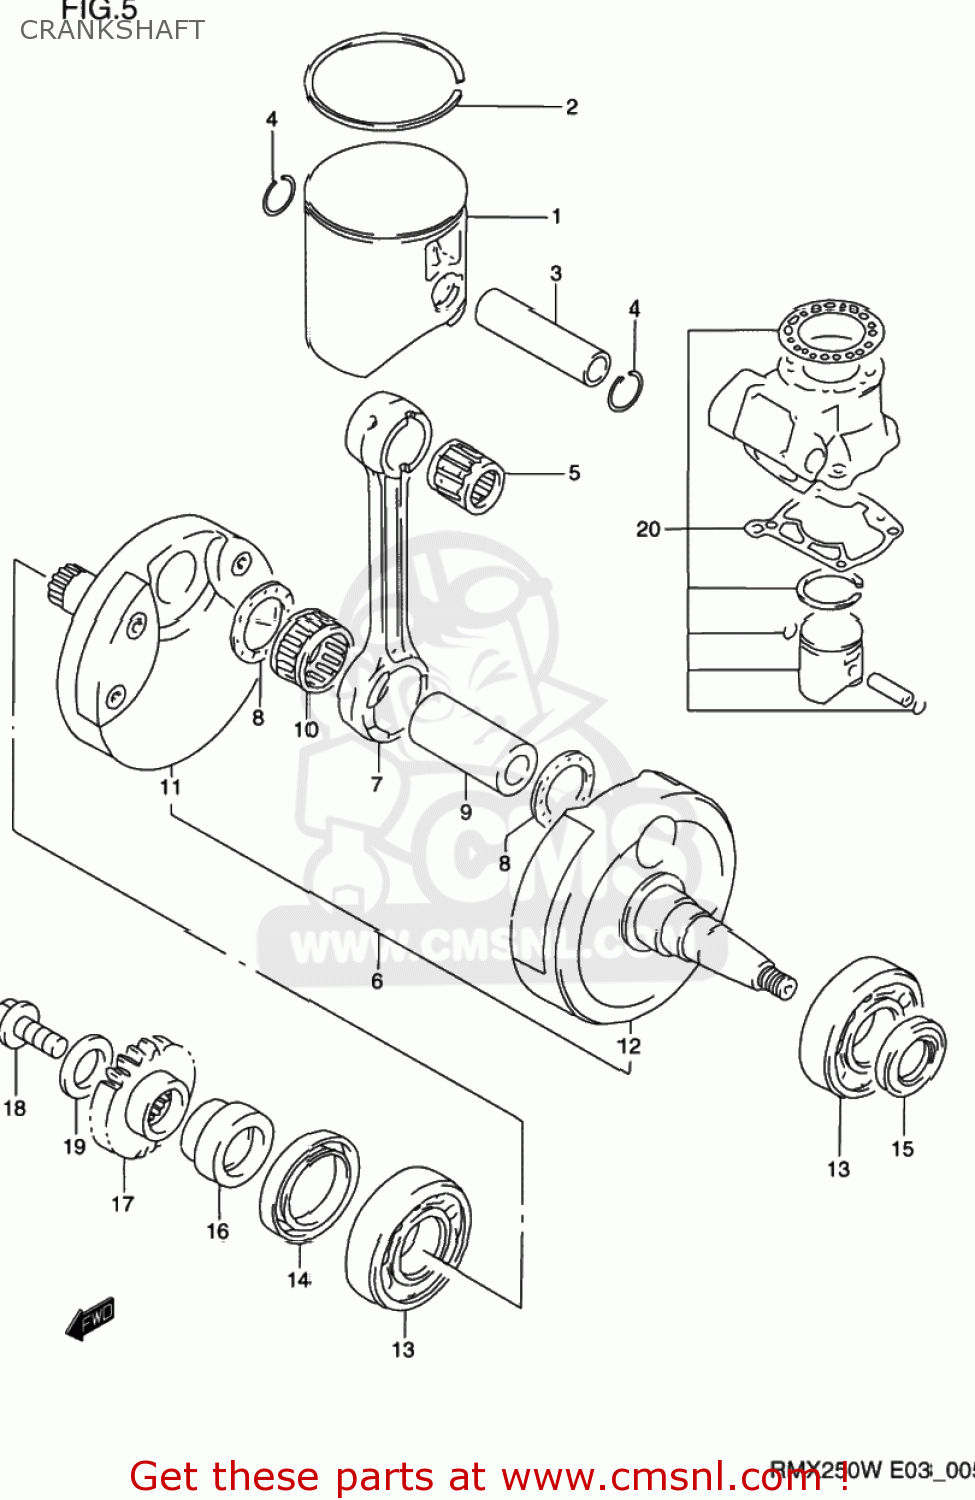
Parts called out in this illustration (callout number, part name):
1	PISTON
2	RING,PISTON
3	PIN,PISTON
4	CIRCLIP
5	BEARING(18X23X22)
6	CRANKSHAFT ASSEMBLY
7	ROD,CONNECTING
8	WASHER(24X38.5X1.5)
9	PIN,CRANK
10	BEARING(24X30X20)
11	CRANKSHAFT,R
12	CRANKSHAFT COMP,LEFT
13	BEARING(28X68X18)
14	SEAL,OIL(38X52X8)
15	SEAL,OIL(25X37X6)
16	SPACER,PRIMARY DRIVE GEAR
17	GEAR,PRIMARY DRIVE
18	BOLT,PRIMARY DRIVE GEAR
19	WASHER
20	TOP END KIT,ENGINE
